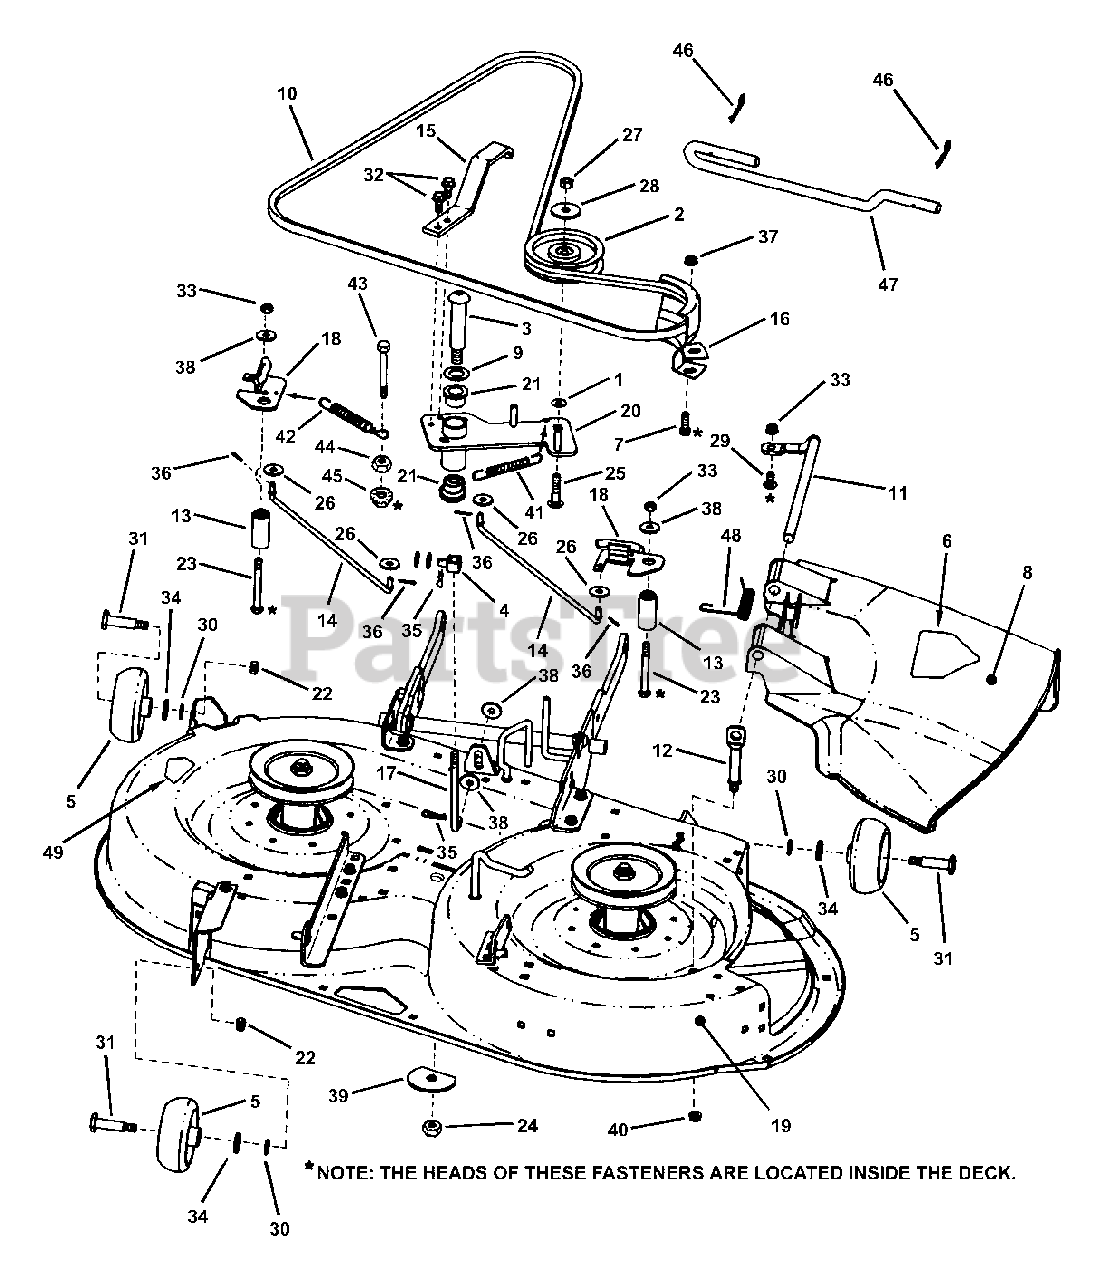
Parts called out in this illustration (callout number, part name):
1	RETAINER, 3/8" Bolt
2	IDLER, 4-1/8" Flat
3	BOLT, 3/4" Dia. X 3.01 Shoulder; 1/2-13 Thread
4	SWIVEL, Brake Link
5	WHEEL, Gage 38" Deck
6	DECAL, CPSC Cut Finger
7	SCREW, 5/16-18 x 1" Hex Head Cap, Grade 5
8	CHUTE, Discharge 38" Deck
9	WASHER, 3/4" I.D. Flat
10	BELT, 38" Deck Dual Spindle Brake
11	ROD, Pivot, Side Discharge
12	ROD, Mounting, Side Discharge
13	PIVOT, Dual Brake
14	BRAKE LINK, Dual Spindle Brake
15	LEVER, Engagement
16	GUARD, Belt, 38" Dual Spindle Brake
17	J-BOLT, 3/8-16 x 6-1/4"
18	ARM, Brake
19	ASSEMBLY, 38" Dual Brake Deck
20	ARM, Idler, Dual Brake
21	BEARING, 3/4" I.D.
22	NUT, 3/8-24 Hex Center Lock, Grade 5
23	SCREW, 5/16-18 x 3" Hex Head Cap, Grade. 5
24	NUT, 1/2-13 Hex Center Lock
25	BOLT, 3/8-16 x 1-3/4" Short Neck Carriage, Grade 5
26	WASHER, 1/4" I.D. Flat
27	NUT, 3/8-16 Hex, Grade 5
28	WASHER, 13/32" I.D. Flat
29	BOLT, 5/16-18 x 3/4" Short Neck Carriage, Grade 5
30	WASHER, 3/8" Flat
31	BOLT, 5/8" Dia. Shoulder, 3/8-24 Thread
32	SCREW, 5/16-18 x 3/4" Self-Tapping
33	NUT, 5/16-18 Hex Center Lock, Grade 5
34	WASHER, 1/2" I.D. Flat
35	PIN, #13 Hair
36	PIN, 3/32 x 3/4" Cotter
37	NUT, 5/16-18 Hex, Grade 5
38	WASHER, 11/32" I.D. Flat
39	WASHER, 1/2" I.D. x 2-1/2" O.D. Special "D"
40	NUT, 3/8-16 Hex Flange Lock
41	SPRING
42	SPRING, Extension
43	SCREW, 1/4-20 x 2-3/4" Hex Head Cap, Grade 5
44	NUT, 1/4-20 Hex, Grade 5
45	NUT, 1/4-20 Hex Flange Lock, Grade 5
46	HAIRPIN (for 5/8" diameter shaft)
47	PIN, Deck Hanger
48	SPRING, Side Discharge
49	DECAL, 38 Inch Deck
